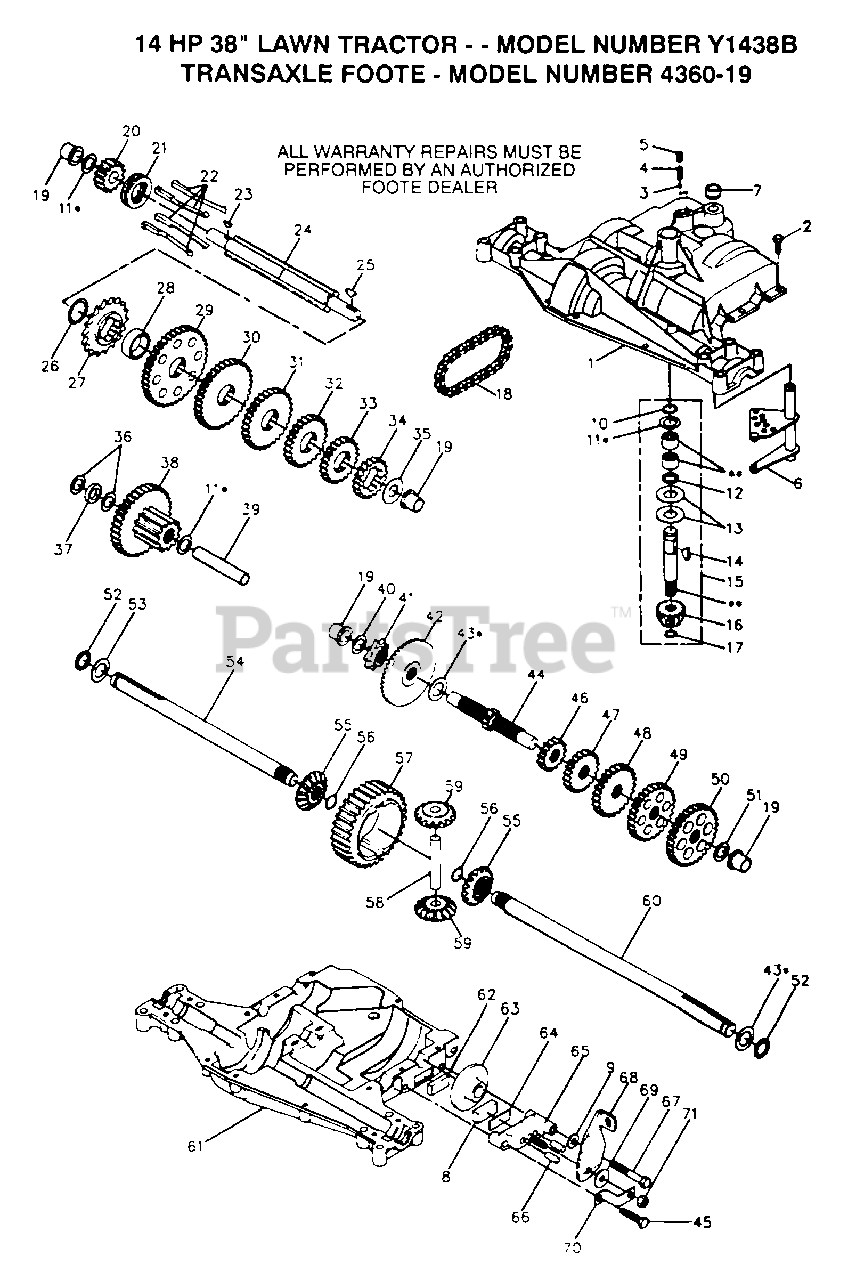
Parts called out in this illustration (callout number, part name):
1	HOUSING UPPER
3	BALL DETENT
4	SPRING, DETENT
5	SCREW, SET
6	ASSEMBLY, SHIFTER
8	PUCK, FRICTION
9	WASHER PLAIN
10	RING RETAINING
11	WASHER PLAIN
11	WASHER, PLAIN .632 X 1.00 X .026
11	WASHER, PLAIN .632 X 1.00 X .060
13	WASHER, PLAIN .632 X 1.38 X .046
14	KEY WOODRUFF #9
15	ASSY KIT INPUT SHAFT
16	PINION BEVEL 14 TEETH
17	RING, RETAINING
18	CHAIN, 24 PITCHES
19	BEARING, FLANGE
20	GEAR, SPUR 14T
21	COLLAR CLUTCH
22	KEY CLUTCH
23	KEY WOODRUFF #3
25	KEY, WOODRUFF, #61
26	RING, RETAINING
27	SPROCKET, 18 TEETH
29	GEAR, SPUR 40T
30	GEAR, SPUR, 35 TEETH
31	GEAR, SPUR, 30 TEETH
32	GEAR, SPUR, 25 TEETH
33	GEAR, SPUR, 22 TEETH
35	WASHER, PLAIN .640 X 1.37 X .061
36	WASHER, PLAIN .632 X 1.00 X .026
37	SPACER .630 X 1.00 X .169
38	ASSY, GEAR, COMB., 12T & 35T
39	SHAFT, IDLER
41	SPROCKET, 9 TEETH
42	GEAR, BEVEL, 42 TEETH
43	WASHER PLAIN
43	WASHER, PLAIN .758 X 1.25 X .031
45	SCREW TAPPING
46	GEAR SPUR, 15 TEETH
47	GEAR, SPUR, 20 TEETH
48	GEAR, SPUR, 25 TEETH
49	GEAR, SPUR, 28 TEETH
50	GEAR, SPUR, 31 TEETH
51	WASHER, PLAIN .632 X 1.00 X .060
53	WASHER PLAIN
54	AXLE LEFT HAND
55	GEAR MITER 15 TEETH
56	RING, RETAINING
57	GEAR, SPUR, 32 TEETH
58	SHAFT, CROSS
59	GEAR, MITER, 15 TEETH
60	AXLE, R.H.
61	HOUSING LOWER
62	PUCK, FRICTION
63	DISC, BRAKE
65	JAW, BRAKE
66	PIN, DOWEL
67	SCREW TAPPING
68	LEVER, ACTUATING
69	WASHER, PLAIN .321 X 1.00 X .055
70	BRACKET, ANTI-ROTATION
71	LOCKNUT 5/16-24
